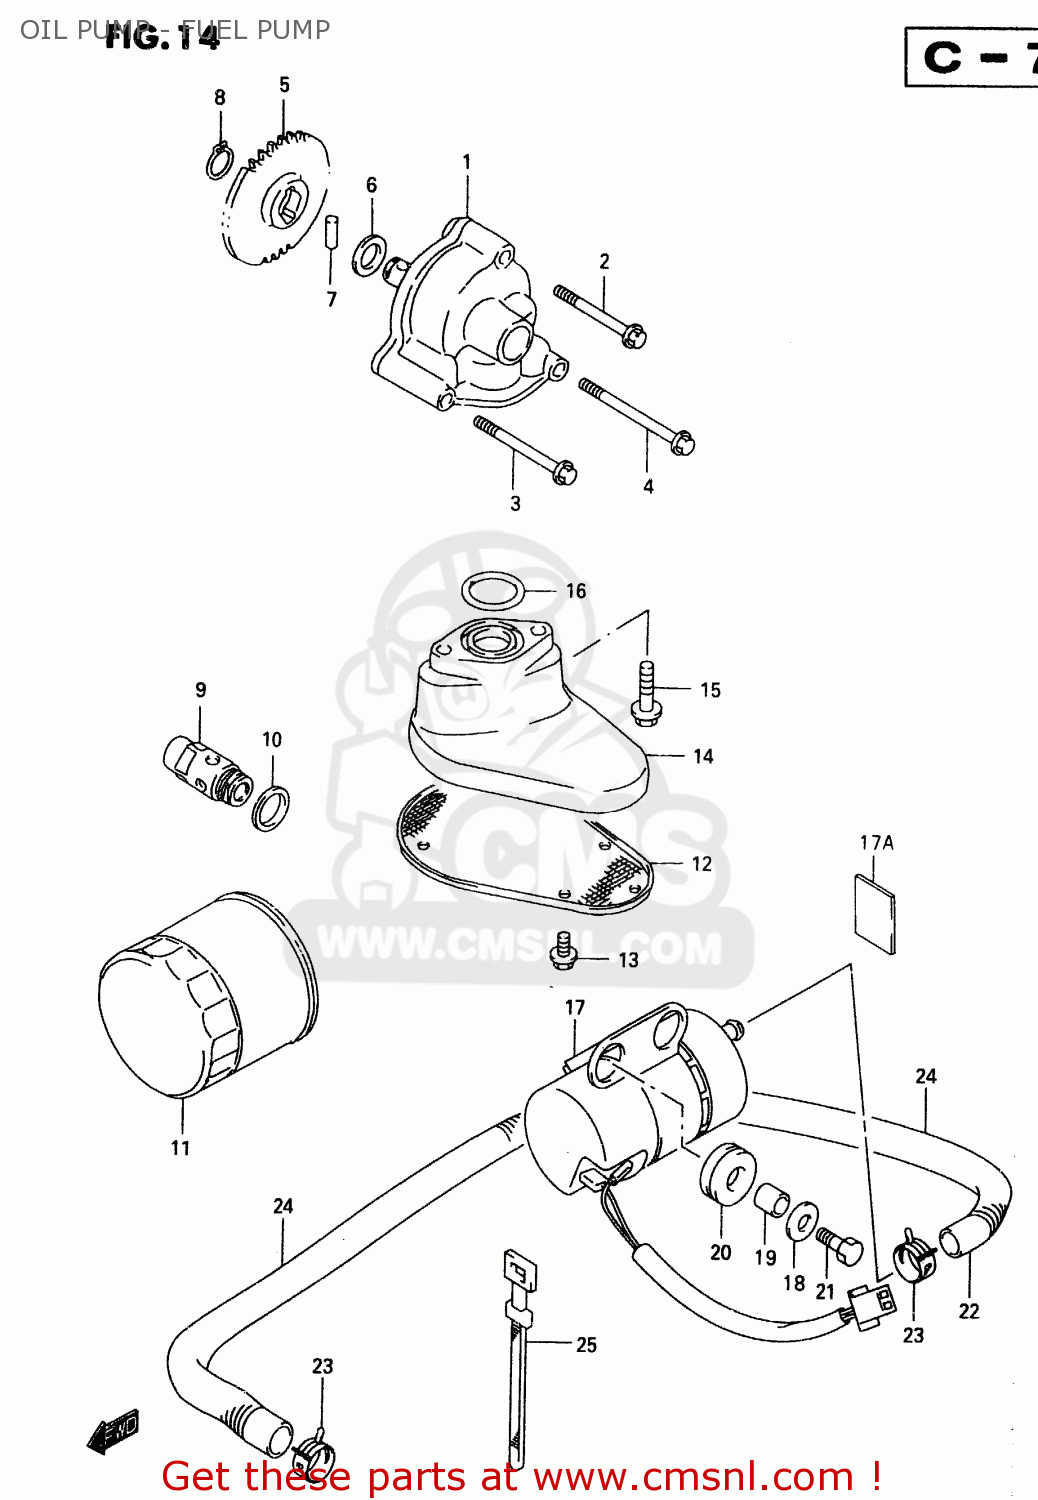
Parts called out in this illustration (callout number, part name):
1	PUMP ASSY,ENGINE OIL
2	BOLT
3	BOLT
4	BOLT
5	GEAR,OIL PUMP DRIVEN
6	SHIM(12X20X0.5)
7	PIN(5X18)
8	CIRCLIP,12 MM
9	VALVE ASSY,OIL RELIEF
10	GASKET(16X22X2) (NAS)
11	FILTER ASSEMBLY,ENGINE OIL
12	STRAINER,ENGINE OIL
13	BOLT
14	HOLDER,OIL STR
15	BOLT
16	O RING(D:3.1,ID:22.7)
17	PUMP ASSY,FUEL
17A	CUSHION,CHAIN CASE
18	WASHER(6.5X20X1.2)
19	SPACER(6.5X9X9)
20	CUSHION
21	BOLT
22	HOSE,FUEL PUMP & CARB
23	CLIP
24	SPRING
25	CLAMP(L:165)
